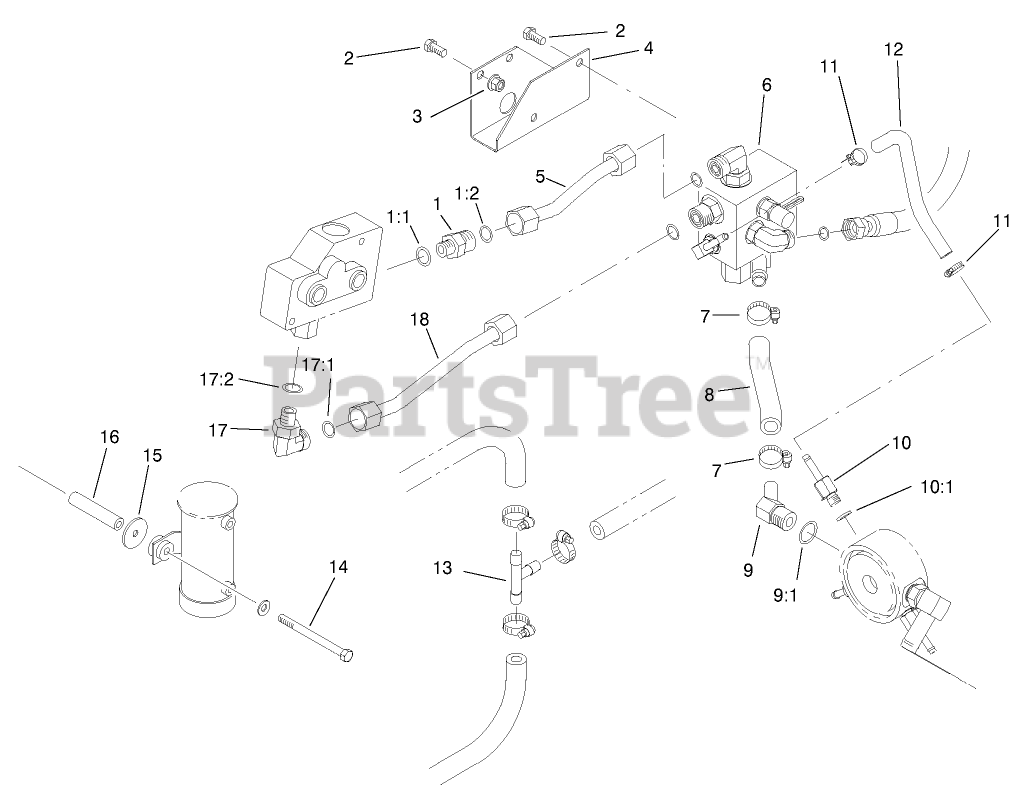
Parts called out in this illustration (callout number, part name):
1	FITTING-STR
1:1	O-RING
1:2	O-RING
2	SCREW-HHF
3	NUT-HF
4	BRACKET-MANIFOLD
5	TUBE ASM
6	MANIFOLD ASM
7	CLAMP-HOSE
8	HOSE-HYDRUALIC
9	FITTING-HYD, 45 DEG
9:1	O-RING
10	FITTING-HOSE, BARBED
10:1	O-RING
11	CLAMP-WORM
12	HOSE-HYDRAULIC
13	FITTING-HYD, TEE
14	SCREW-HH
15	WASHER-FLAT
17	FITTING-HYD, 90 DEG
17:1	O-RING
17:2	O-RING
18	TUBE ASM
